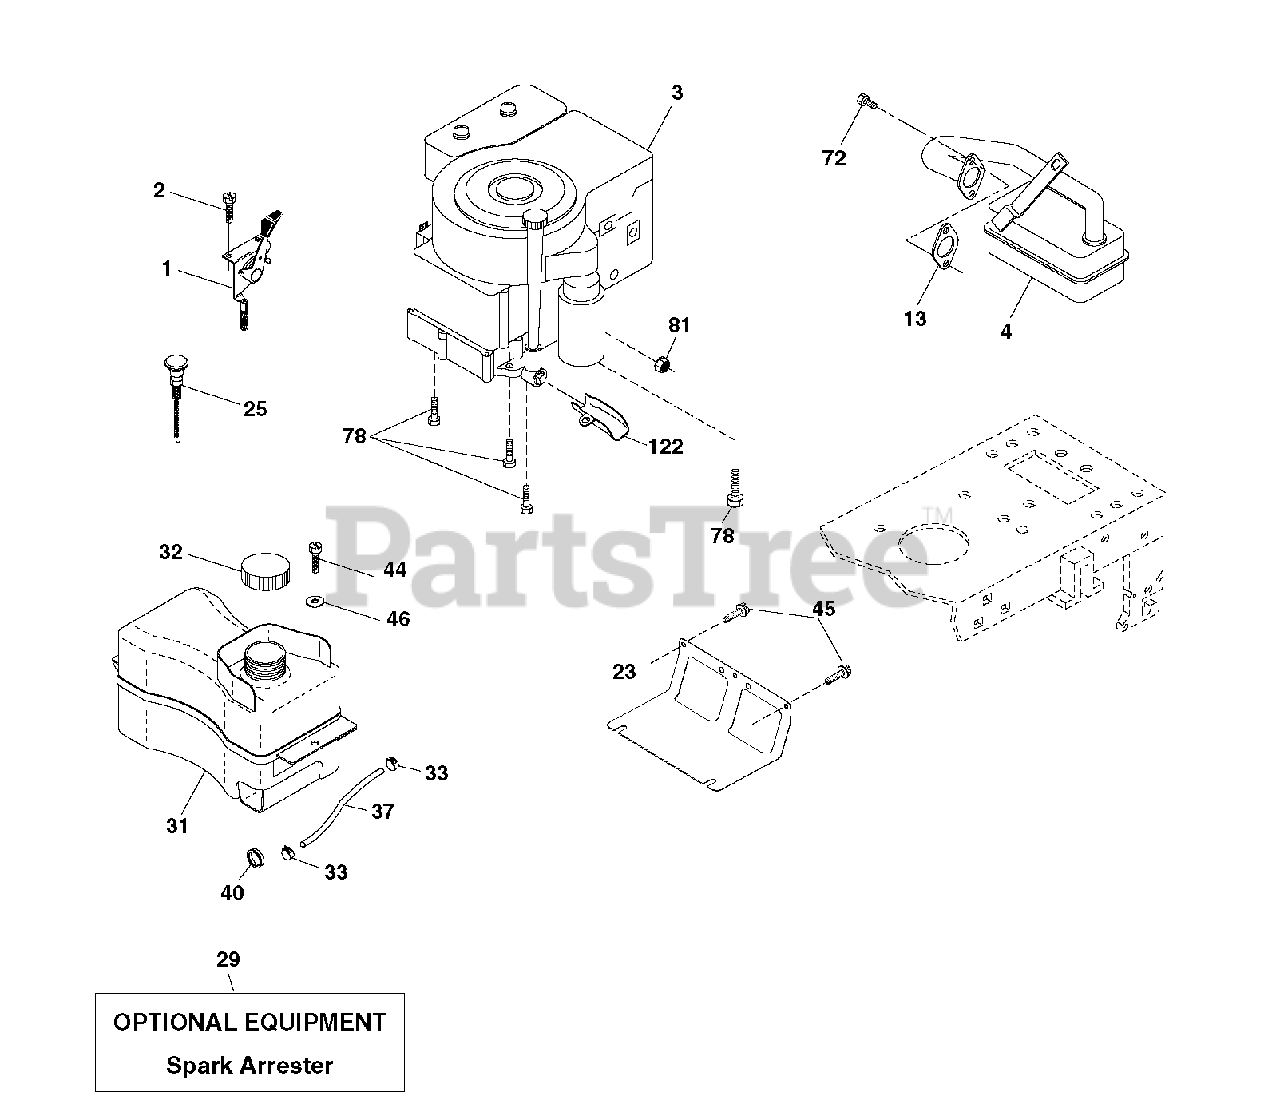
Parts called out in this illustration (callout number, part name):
1	CONTROL TH/CH FLAG
2	SCREW
13	REPL BY 532 27 22-93
23	SHEILD.BROWNING.DBR.GUARD
25	KNOB.ERGO.EXTENDED.RED (1 2)
29	ARRESTER SPARK (OPTIONAL)
32	CAP ASM.FUEL.2.25"FR.
37	LINE.FUEL.20
44	SCREW HEXWSHR 1/4-20X3/4
45	SCREW, 3/8-16X3/4
72	SCREW.SOCKET HD.5/16-1
81	NUT
122	EXTENSION DRAIN OIL
